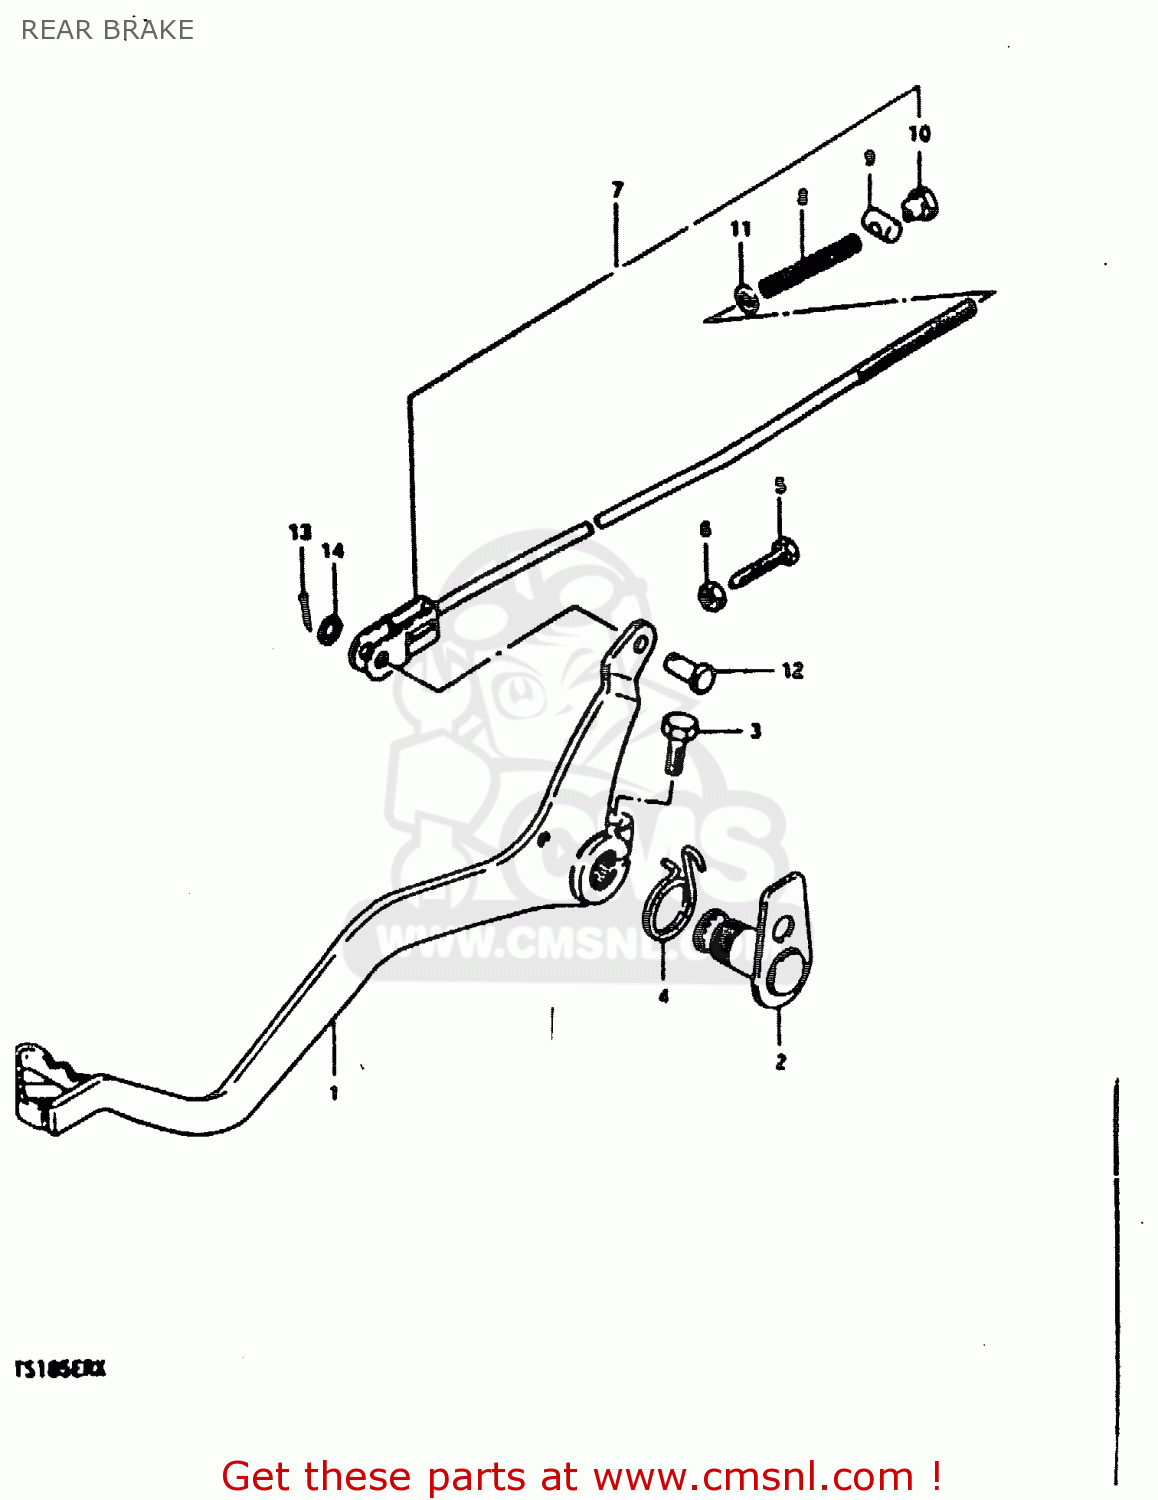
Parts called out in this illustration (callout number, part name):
1	PEDAL,BRAKE
2	ARM,BRAKE PEDAL
3	BOLT
4	SPRING
5	BOLT(6X23)
6	NUT
7	ROD ASSY,RR BRAKE
8	SPRING
9	PIN
10	NUT
11	WASHER
12	PIN(L:13.5)
13	PIN 20X20
14	WASHER
